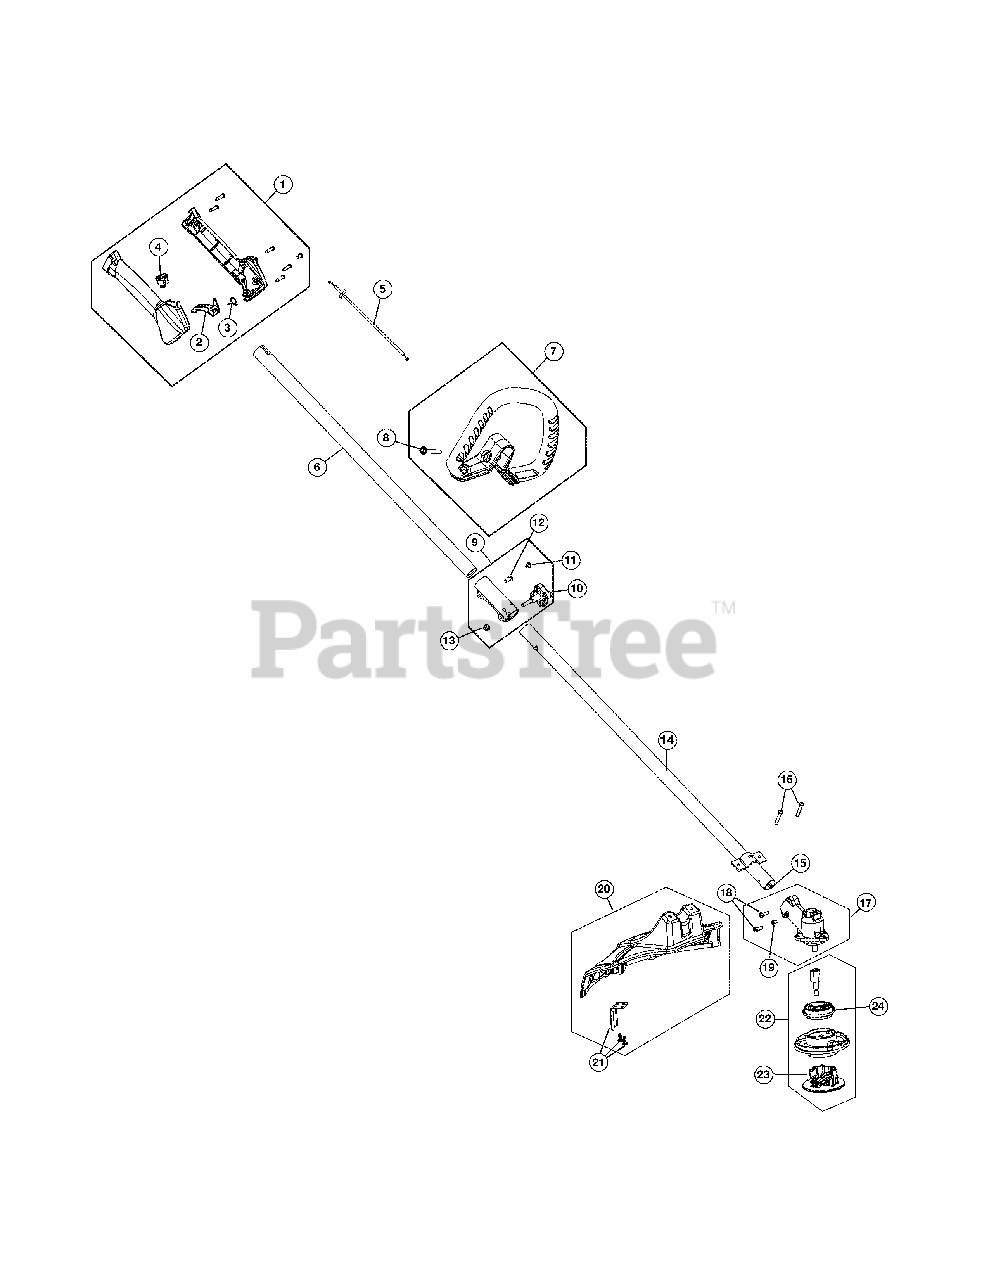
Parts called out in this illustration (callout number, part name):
1	Throttle Housing Assembly (Incl Ref No. 2-4)
2	Throttle Trigger
3	Throttle Trigger Spring
4	Switch Assembly
5	Throttle Cable Assembly
6	Upper Drive Shaft Assembly
7	D-Handle Assembly (Incl Ref No. 8)
9	Split Boom Coupler (Incl Ref No. 10-13)
10	Adjustment Knob (Incl Ref No. 13)
11	Coupler Anti-Rotation Screw
12	Coupler Bolt
13	Adjustment Knob Nut
14	Lower Drive Shaft Housing
15	Lower Flexible Drive Shaft
16	Shield Mount Screw Assembly
17	Gearbox Assembly (Incl Ref No. 18 & 19)
18	Gearbox Screw
19	Gearbox Anti-Rotation Screw
20	Shield Assembly (Incl Ref No. 21)
21	Blade Assembly
22	Cutting Head Assembly (Incl Ref No. 23 & 24)
23	Cutting Head Cap
